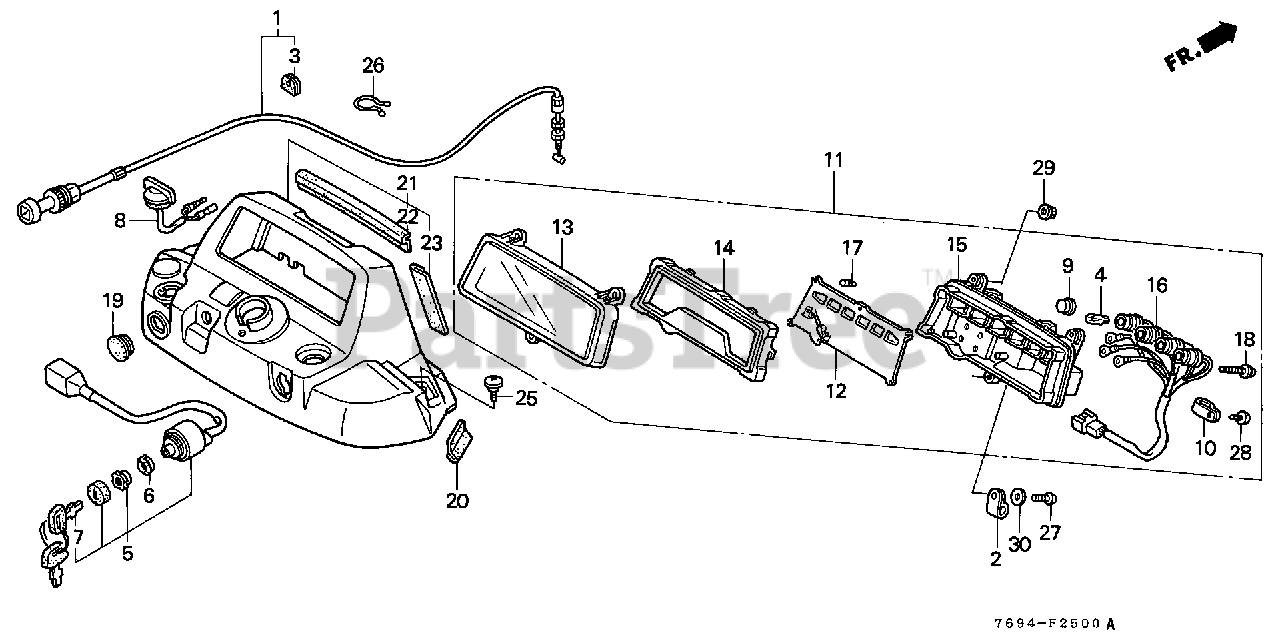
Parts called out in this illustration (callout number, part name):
1	CABLE, CHOKE
2	CLAMP, IGNITION WIRE
3	GROMMET, WIRE
4	BULB, WEDGE BASE (12V 3.4W)
4	BULB (12V3.4W) (158)
4	BULB (12V3.4W2CP) (158) (NS)
5	SWITCH ASSY., COMBINATION
6	BASE, COMBINATION SWITCH
7	KEY ASSY., COMBINATION SWITCH
8	SWITCH ASSY., ENGINE STOP
11	INDICATOR ASSY.
12	METER, FUEL
14	PLATE, REFLECTING
17	RUBBER, CUSHION
18	SCREW-WASHER (3X22)
19	GROMMET, CARRYING HANDLE
20	SEAL D, COLUMN COVER (45MM)
21	PANEL, INSTRUMENT *NH105* (MAT BLACK)
22	SEAL, INSTRUMENT
23	SEAL, INSTRUMENT SIDE
25	SCREW, METER VISOR SETTING
26	CLIP, PURSE LOCK
27	SCREW, PAN (5X25)
28	SCREW, TAPPING (4X16)
29	NUT, FLANGE (5MM)
30	WASHER, PLAIN (5MM)
